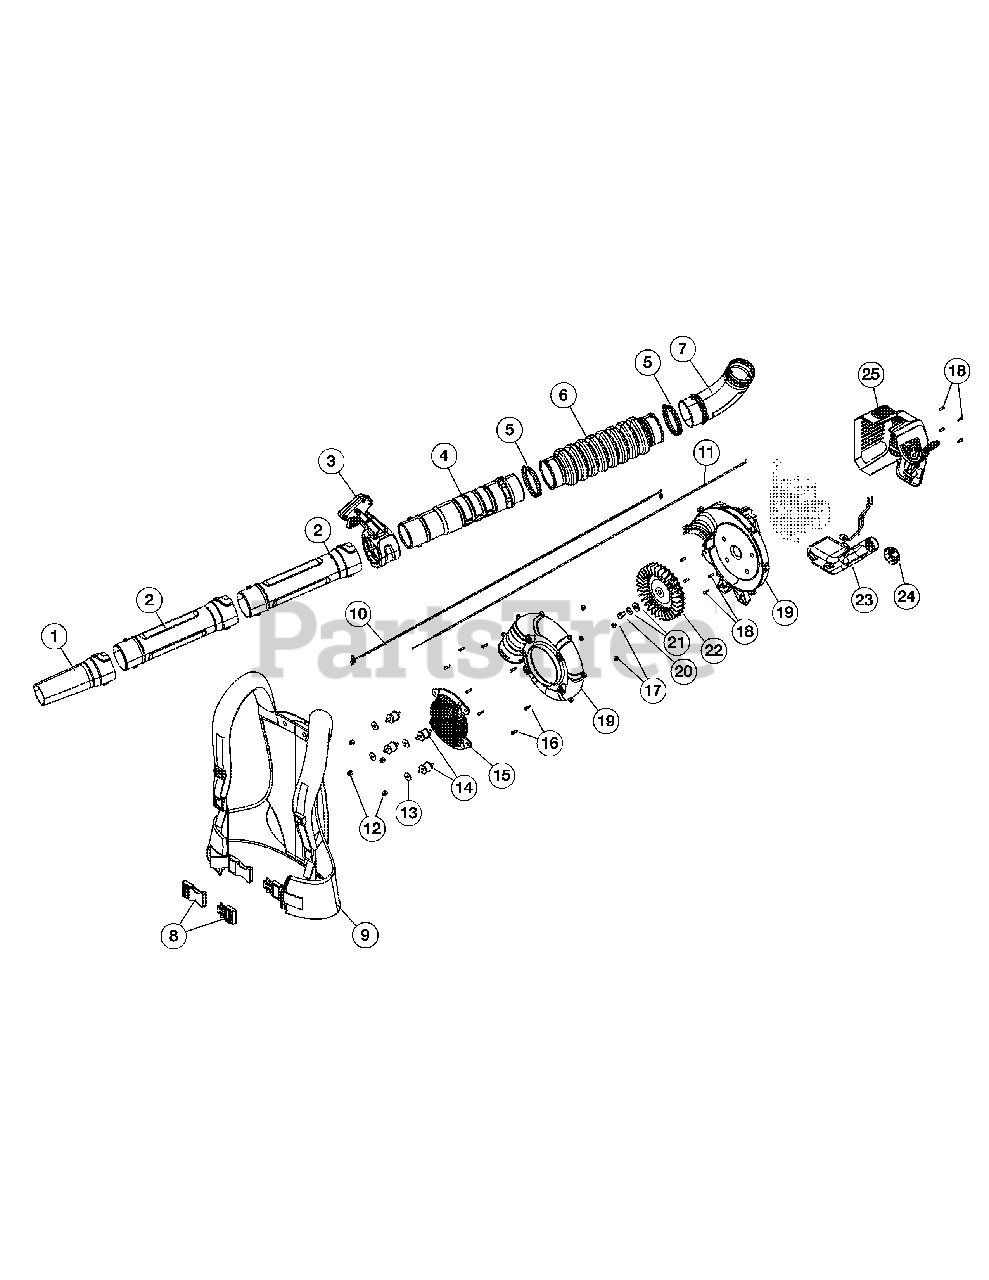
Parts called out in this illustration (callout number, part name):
1	Nozzle
2	Lower Blower Tube
3	Throttle Grip Assembly
4	Upper Blower Tube
5	Clamp
8	Waist Support Clip
9	Suspension System
11	Throttle Cable
12	Nut
13	Spacer
14	Insulator Mount
15	Intake Cover
17	Nut
18	Screw
19	Impeller Housing Assembly
21	Impeller Hardware
22	Impeller
23	Fuel Tank Assembly
25	Starter Housing Assembly
